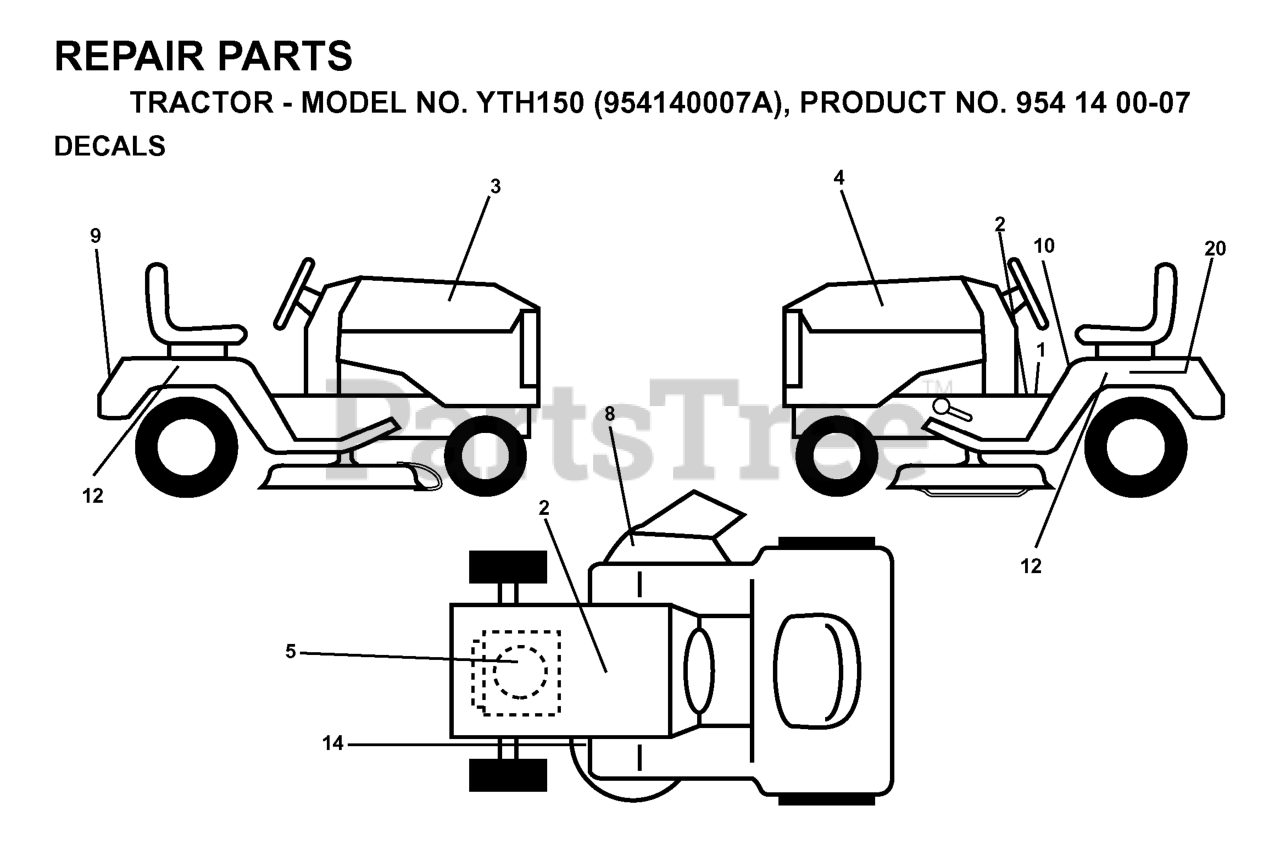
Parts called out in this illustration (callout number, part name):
2	DECAL, BATTERY DANGER
3	DECAL, HOOD LH YTH150
4	DECAL, HOOD RH YTH150
8	DECAL WARNING (ENGLISH/FRENCH)
9	DECAL FENDER HUSQ
10	DECAL FENDER DANGER
14	DECAL V-BELT SCHEMATIC
